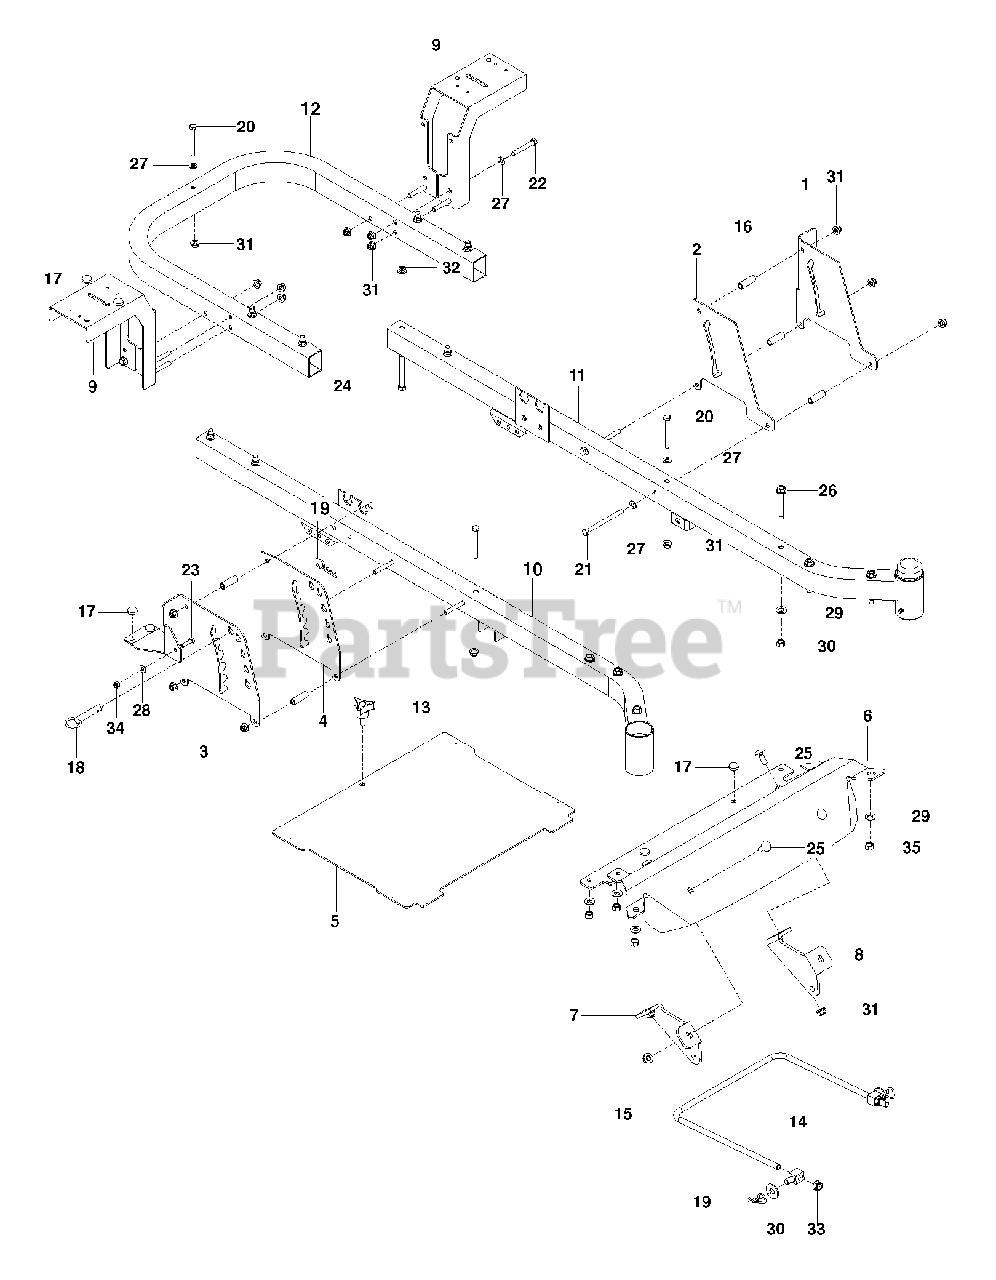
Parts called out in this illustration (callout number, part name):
1	PLATE, OUTER BRAKE, BLACK
2	PLATE, BRAKE LATCH, BLACK
3	PLATE, DECK HEIGHT, BLK EZ
4	PLATE, DECK HEIGHT, BLACK
5	PLATE, FOOT W/DECALS RZ
6	FOOT.REST.MED.ORANGE
7	MOUNT, STRUT, RT, BLK
8	MOUNT, STRUT, LT, BLK
9	SUPPORT, FENDER, BLACK
10	FRAME, RT, ORANGE
11	FRAME, LT, ORANGE
12	FRAME TUBE, REAR ORG
13	KNOB W/STUD
15	LINK, FRONT SUSP.
16	SPACER, .334 ID X .5 OD X 1.5
17	GROMMET, BUMPER
19	HAIRPIN #4
22	BOLT.FIN HEX 5/16-18UNC X2 1/4
24	BOLT.HEX.FIN.3/8-16 X 3.GR5
27	WASHER
29	WASHER 3/8 FLAT
30	WASHER.9/16 X 1 3/8 X 12 GA.
31	5/16-18 NYLOC FLANGE NUT
32	NUT 3/8-16 HEX FLG NYLOC ZD
33	7/16-14 HEX NUT W/NYL RING ZD
34	LOCKNUT.NYLOC.1/4-20
35	NUT HEX 3/8-16 NYLON, THIN
